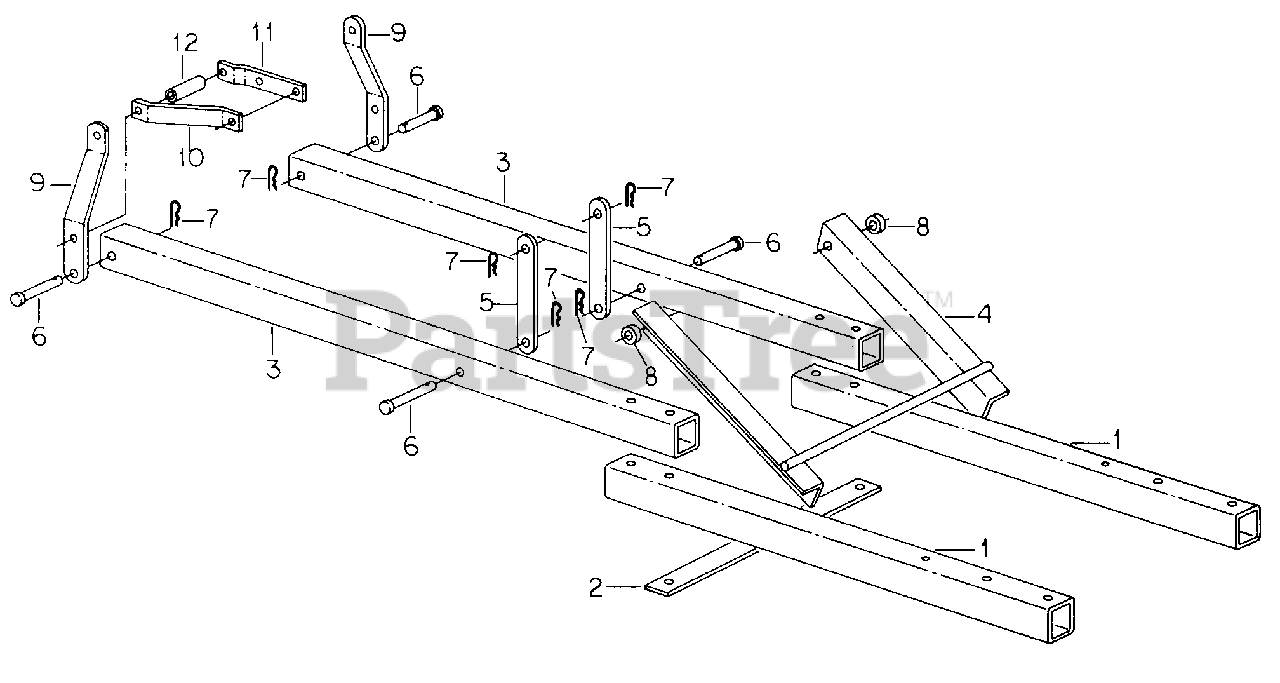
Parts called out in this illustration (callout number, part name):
1	Tube, Frame Front
2	Support, Tube
3	Tube, Frame Rear
4	Bracket Assy, Frame Guide
5	Strap, Frame Lift
6	Pin, 1/2 X 2.766 Pln Clevis
7	Pin, No. 3 Quick Attach Cotter
8	Spacer, Shoulder
9	Strap, Rear Hanger
10	Support, Rear Hanger
11	Strap, Mounting LH
12	Spacer, .50 ID X 1.0 OD X 1.47
